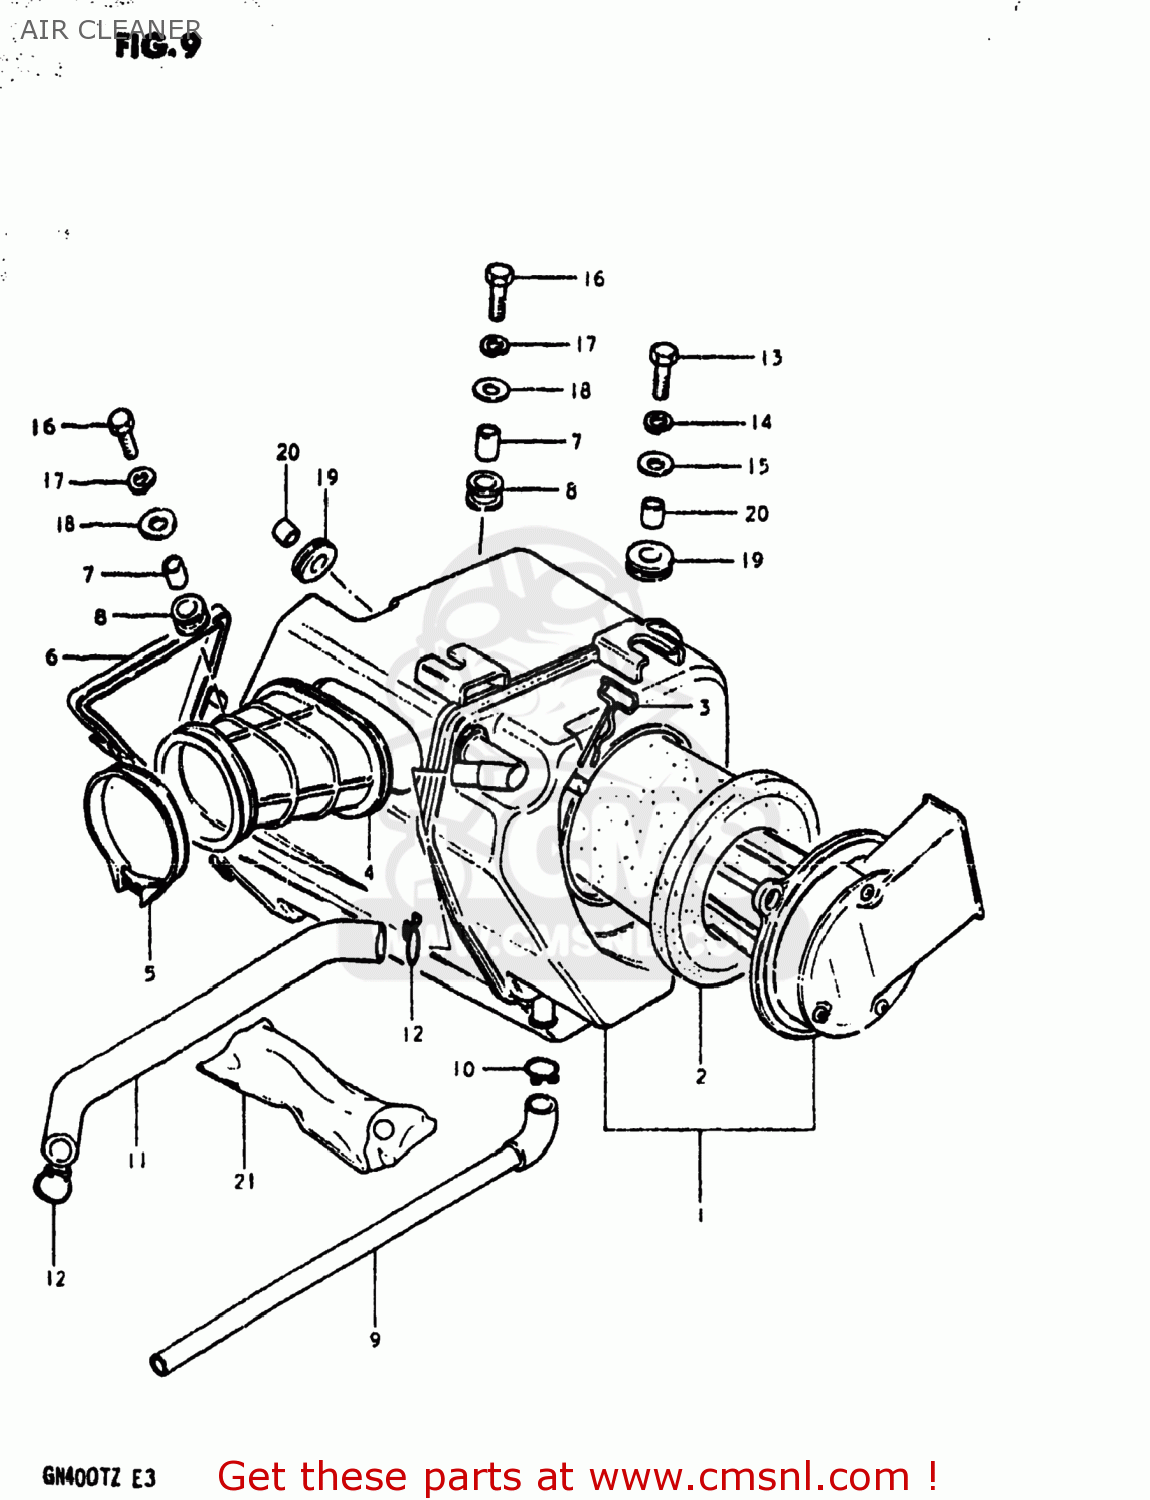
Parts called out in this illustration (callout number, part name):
1	CLEANER ASSEMBLY,AIR
2	FILTER ASSY
3	SNAP PIN,AIR CLEANER
4	TUBE,AIR CLEANER OUTLET
5	CLAMP
6	CAP,TOOL BOX
7	SPACER (6.8X10X10)
8	CUSHION
9	DRAIN TUBE
10	CLIP
11	TUBE,BREATHER
12	CLIP
13	BOLT
14	LOCK WASHER
15	WASHER
16	BOLT
17	LOCK WASHER
18	WASHER
19	CUSHION
20	SPACER(6.5X10.5X6.5)
21	TOOL SET
